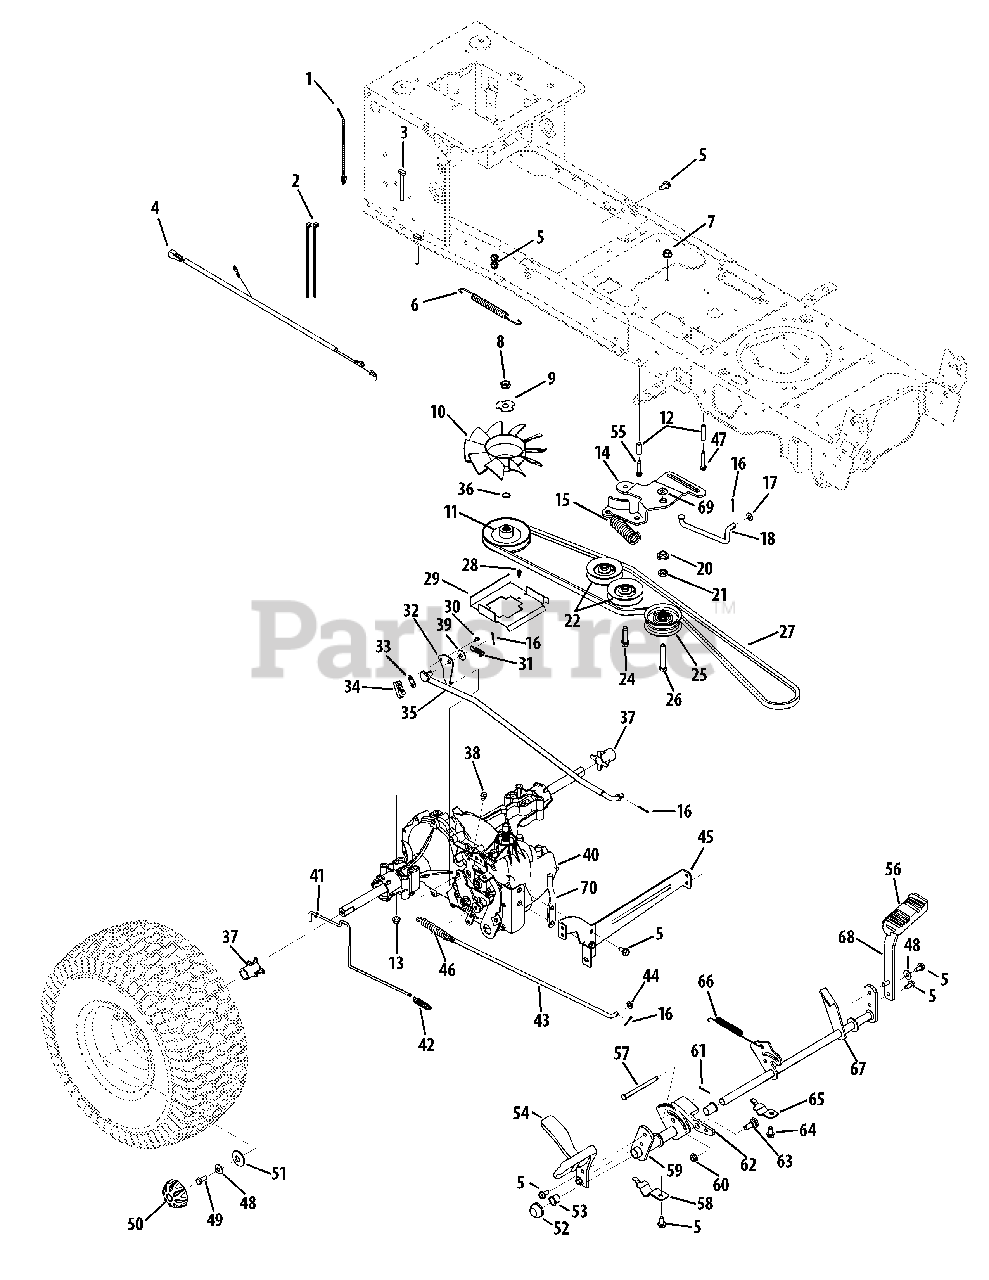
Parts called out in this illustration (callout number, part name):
1	Cable Tie, 7.5
2	Cable Tie, 3/16 x .05 x 7.4
3	Hex Bolt 5/16-18 x 2.75
4	Jumper Harness
5	S-Tapp Screw 5/16-18 x .75
6	Extension Spring .50 dia. x 12.6
7	Flange Locknut 3/8-16 Gr. F
8	Jam Locknut 1/2-10
9	Lockwasher
10	Hydro Fan
11	In put Pulley
12	Spacer, .260 x .372 x 1.420
13	Flange Locknut 5/16-18 Gr. F, Nylon
14	Idler Bracket
15	Extension Spring .59 x 4.0
16	Cotter Pin 3/32 dia x 1.00 Lg.
17	Flat Washer .330 x .630 x .0635
18	Pedal Transmission By pass Rod
20	Shoulder Spacer 1.375 x .38 x .183
21	Hex Jam Nut 7/16-20
22	Idler Pulley
24	Hex L-Wash HD Screw 3/8-16 x 1.5
25	Idler Pulley, Flat 2.75 OD
26	Hex Bolt 3/8-16 x 2.25" Lg.
27	V-Belt
28	Truss Mach B-Tapp Screw #10 X .50
29	Belt Disengage Support Bracket
30	Hex Washer Screw #8-18 x .50
31	Extension Spring 3/8 x 1.44
32	Switch Actuator Bracket
33	Insulator Nut Plate
34	Short Spring Switch
35	Hydro Control Rod
36	Wire Ring
37	Sleeve 0.765 x 1.5
38	Hex Wash HD Tapp Screw 1/4-20 x .375
39	Flat Washer .406 ID x .812 OD x .134
40	Hydro Transmission
41	Hydro By pass Rod
42	Extension Spring .47 OD x 2.03 Lg.
43	Brake Rod
44	Flat Washer .312 ID x .75 OD
45	Hydro Mount Bracket
46	Extension Spring .59 x 4.0
47	Hex Washer Hd. TT Screw 1/4-20 x 1.75
48	Cupped Washer .345 ID x .88 OD x .060
49	Hex L-Bolt 5/16-24 x .75 Gr. 5
50	Hub Cap
51	Flat Washer, .350 x 1.59 x .062
52	Push Cap 5/8" Dia Rod
53	Nyliner Flanged Brg.
54	Control Pedal
55	Hex Washer Hd. TT Screw 1/4-20 x 1.625
56	Brake Pedal Pad
57	Clevis Pin 5/16 x 3.985
58	Transmission Rod Support Strap
59	Hydro Pedal Brkt. Assembly
60	Flange Lock-Nut 3/8-16 Gr. F Nylon
61	Bow-Tie Cotter Pin
62	Cruise Latch
63	Shoulder Screw .500 x .25
64	Self-tap ping Screw 5/16-18 x .625
65	Brake Shaft Support Strap
66	Extension Spring .63 x 4.95
67	Brake Control Assembly
68	Brake Pedal Bracket
69	Flat Washer .385 ID x 1.0 x .030
70	Belt Keeper Rod
